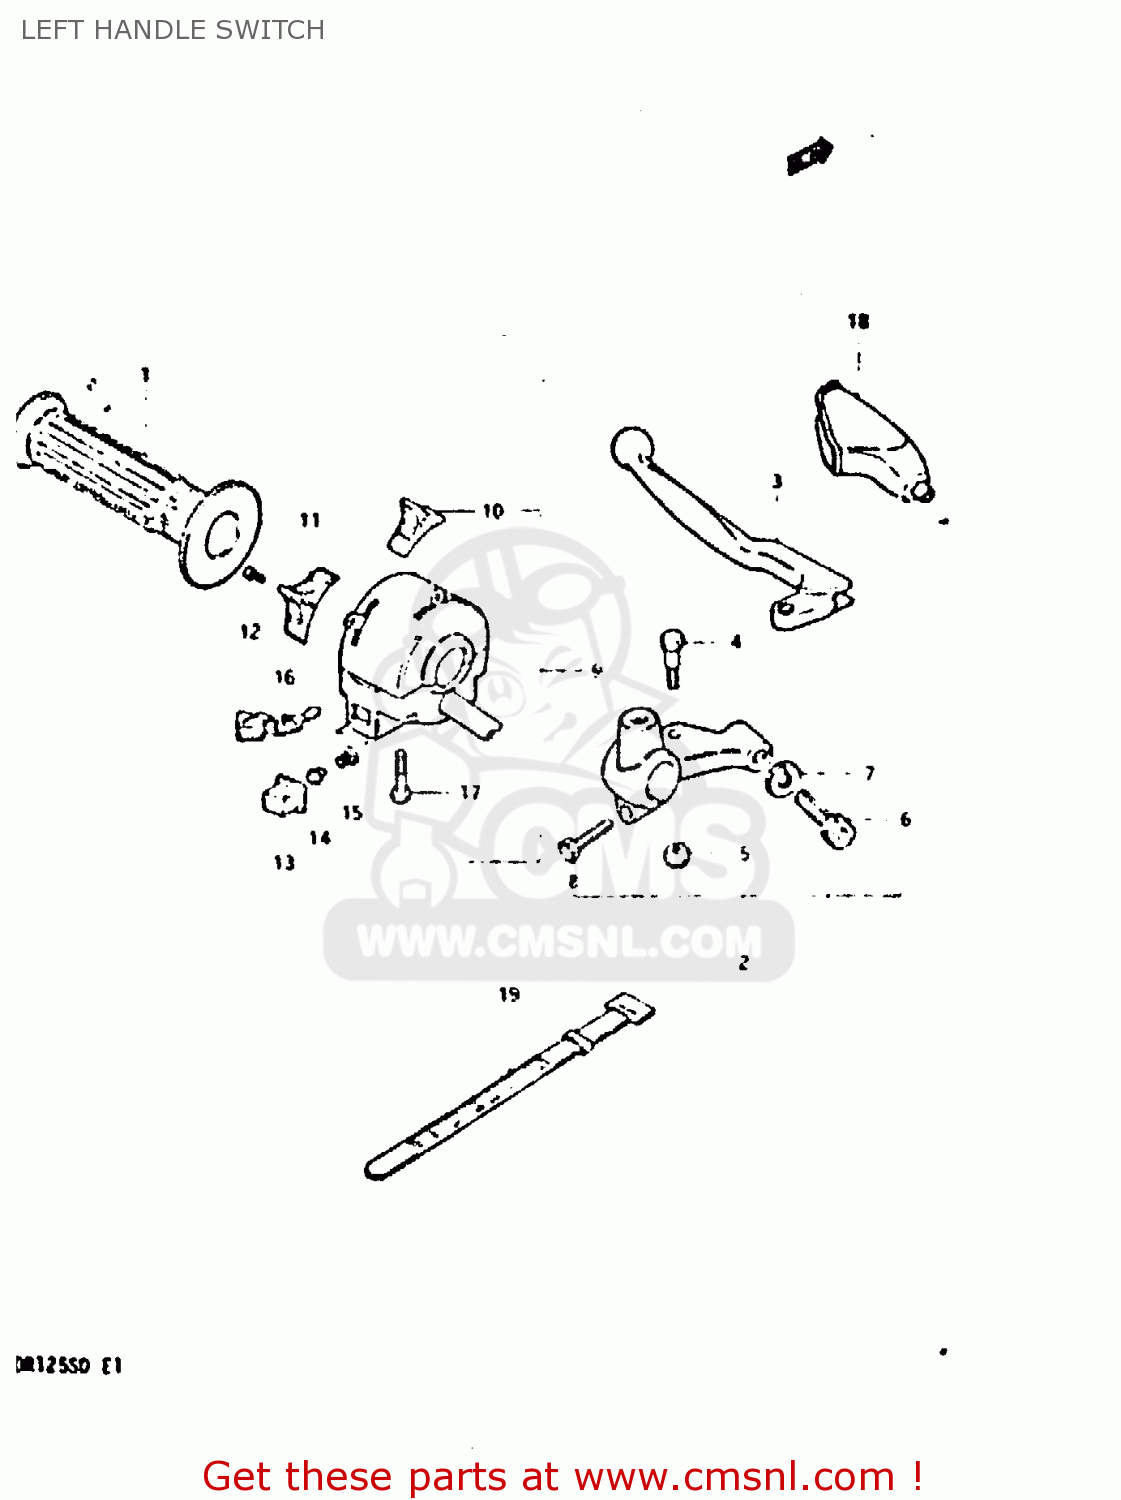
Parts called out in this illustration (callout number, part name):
1	GRIP,L
2	LEVER ASSY,CLUTCH
3	LEVER,CLUTCH
4	BOLT,LEVER
5	NUT 6MM
6	ADJUSTER,CABLE
7	NUT,CABLE ADJUSTER
8	BOLT,CLUTCH LEVER HOLDER
9	SWITCH ASSY, HANDLE LH
10	KNOB,LIGHTING SWITCH
11	KNOB,DIMMER SWITCH
12	SCREW
13	BUTTON,HORN
14	BUTTON,HORN
15	SPRING
16	KNOB,TURNSIGNAL
17	SCREW
18	COVER,CLUTCH LEVER
19	CLAMP(L:120)
